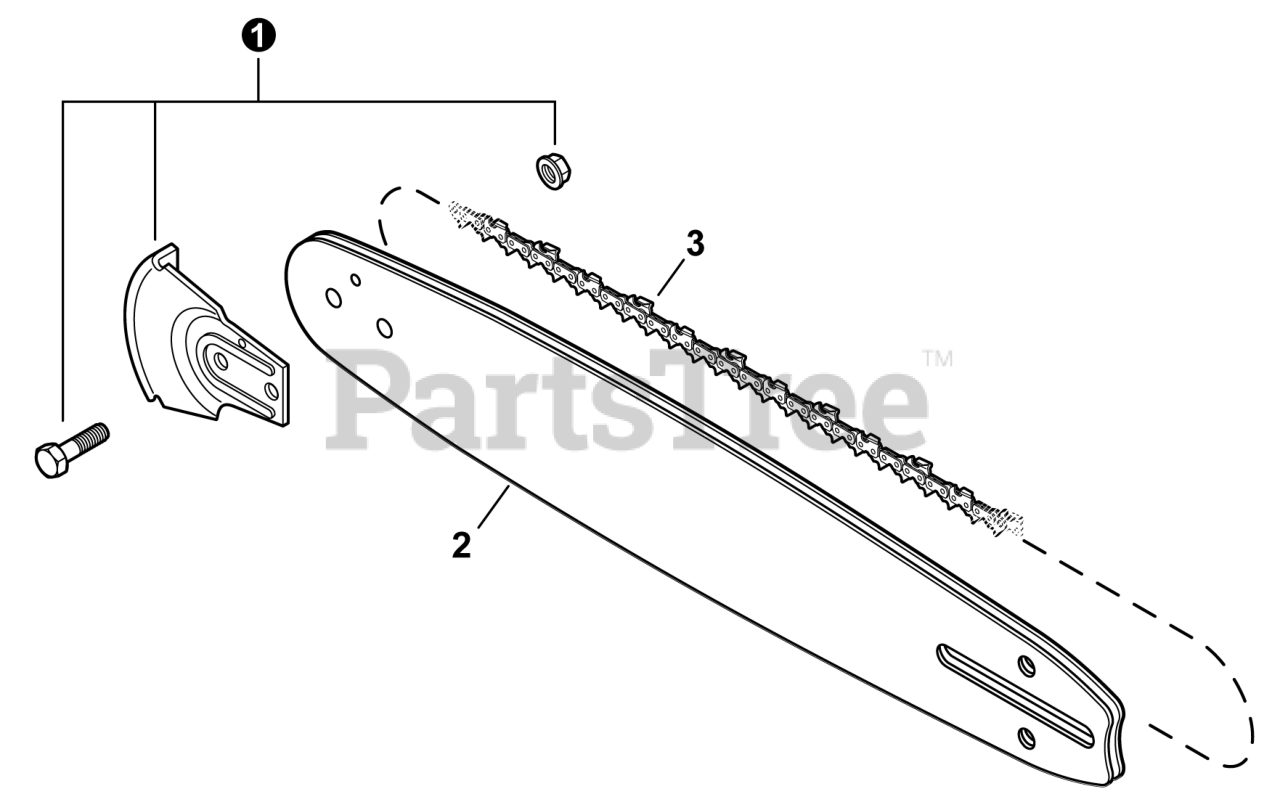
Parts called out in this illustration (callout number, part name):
1	KICK GUARD KIT
2	GUIDE BAR, 16"
2	GUIDE BAR, 18"
3	SAW CHAIN 16"
3	SAW CHAIN 18"
